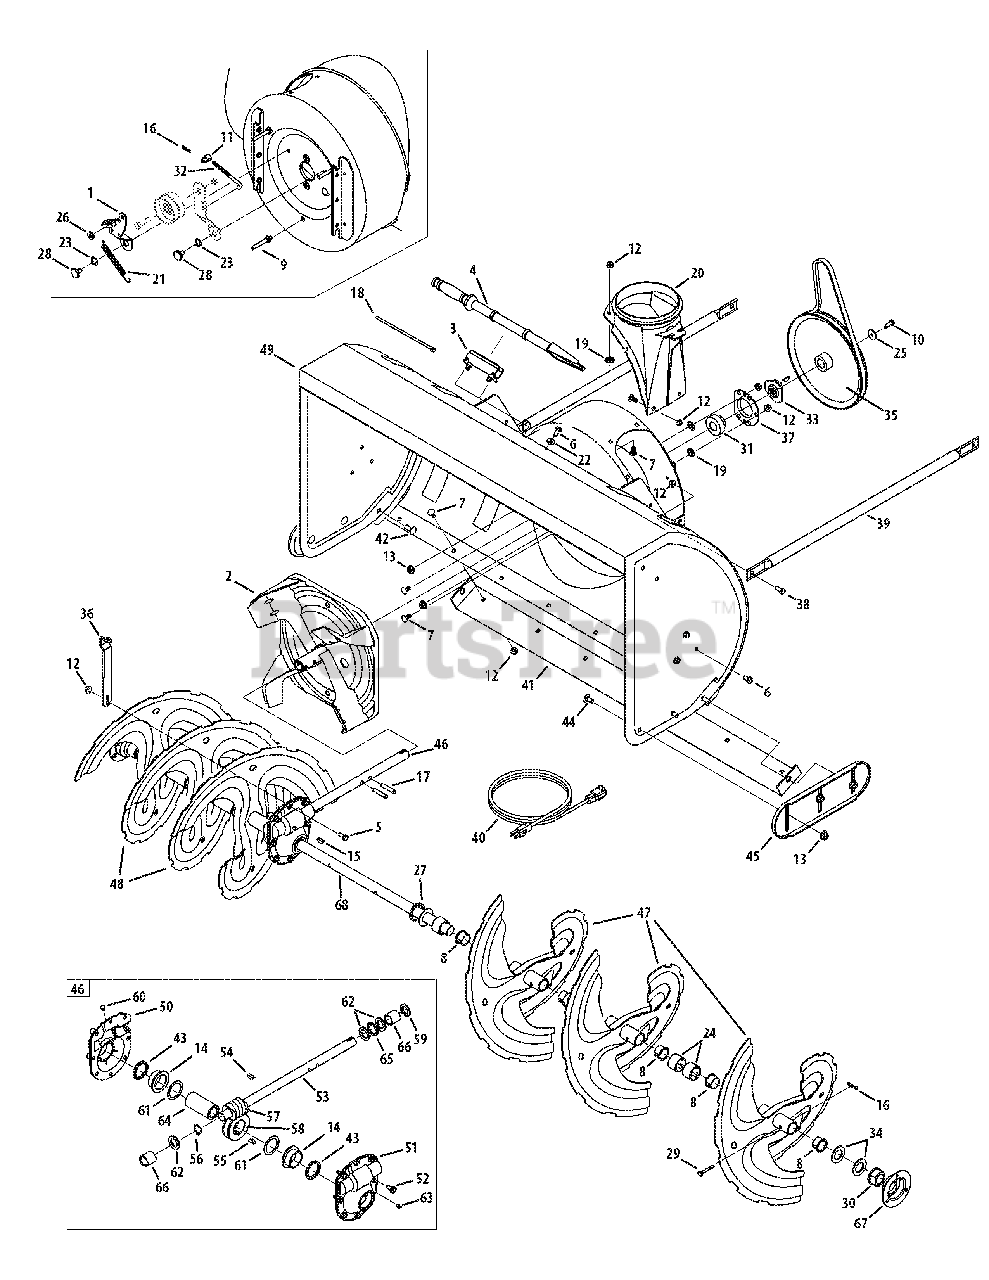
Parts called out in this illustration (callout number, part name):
1	Bracket Assembly, Auger Brake
3	Clip, Mounting
4	Tool, Clean-out
5	Screw, Hex Cap, 5/16-18 x 1.0 Gr5
6	Screw, 5/16-18 x .750
7	Screw, Carriage, 5/16-18 x .75
8	Flange Bushing
9	Screw w/Stud, 5/16-18 x .4300
10	Screw, Hex Cap Lock, 5/16-24 x .875
11	Ferrule
12	Nut, Hex Flange Lock, 5/16-18
13	Nut, Hex Flange Lock, 3/8-16
14	Flange Bearing
15	Key, Woodru, 1/4 x 3/4
16	Pin, Bow-tie Cotter
17	Pin, Spiral, 5/16 x 1.75
18	Cable Tie
20	Adapter, Chute, 6"
21	Spring, Extension
22	Washer, Flat, .349 x .879 .063
23	Washer, Wave, .625 x .885 x .015
24	Spacer, 1.50 x 1.00 x 1.00
25	Washer, Flat, .34 x 1.5 x .15 Ht.
26	Washer, .344 x .75 x .12
27	Washer, 1.01 x 1.86 x .06
28	Screw, Shoulder, .625 x .17
29	Pin, Shear, .25 x 1.75
30	Bearing, Flange w/Flats
31	Bearing, Self Aligning
32	Rod, Auger Idler
33	Adapter, Pulley w/Pins
34	Spacer, 1.004 x 1.375 x .25
35	Pulley, Auger Drive, 10.0
37	Housing, Bearing
38	Screw, 5/16-18 x .75 GR5
42	Bolt, Carriage, 3/8-16 x 1.00
43	Oil Seal
44	Bolt, Carriage, 3/8-16 x .750
46	Gear Box Assembly
50	Housing Assembly, Auger, RH
51	Housing Assembly, Auger, LH
52	Screw, LD, 5/16-18 x .750
53	Auger Drive Shaft
54	Key, Hi Pro, 3/16 x 3/4
55	Key, 1/4 x 3/4 Dia.
56	External Retainer Ring
57	Gear, Worm
58	Gear, Worm, LH
59	Seal, Oil
61	Wash, Flat, 1.52ID x 2.0 OD
62	Wash, Flat, .88 ID x .38 OD
63	Grease Fitting, 3/16
64	Worm Gear Shaft
65	Bearing, Thrust
66	Sleeve
68	Axle, Spiral
